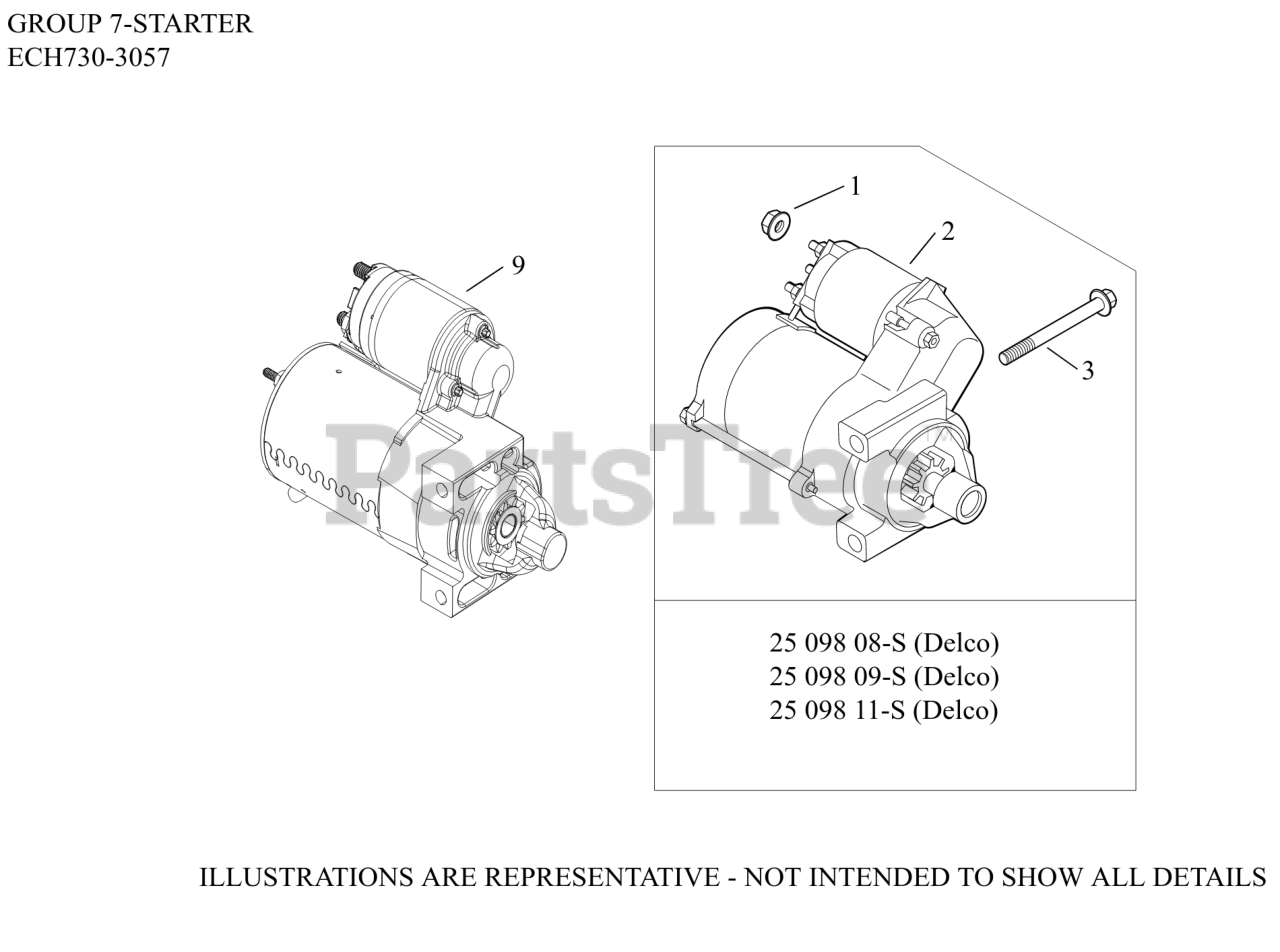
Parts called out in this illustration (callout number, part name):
1	NUT, FLG M8X1.25
2	ELECTRIC STARTER-USE 25 098 20-S
3	SCREW, FLG M8X1.25X80
9	STARTER, SOLENOID SHIFT-USE 25 098 21-S
9	STARTER, SOLENOID SHIFT-(#2509824S)
